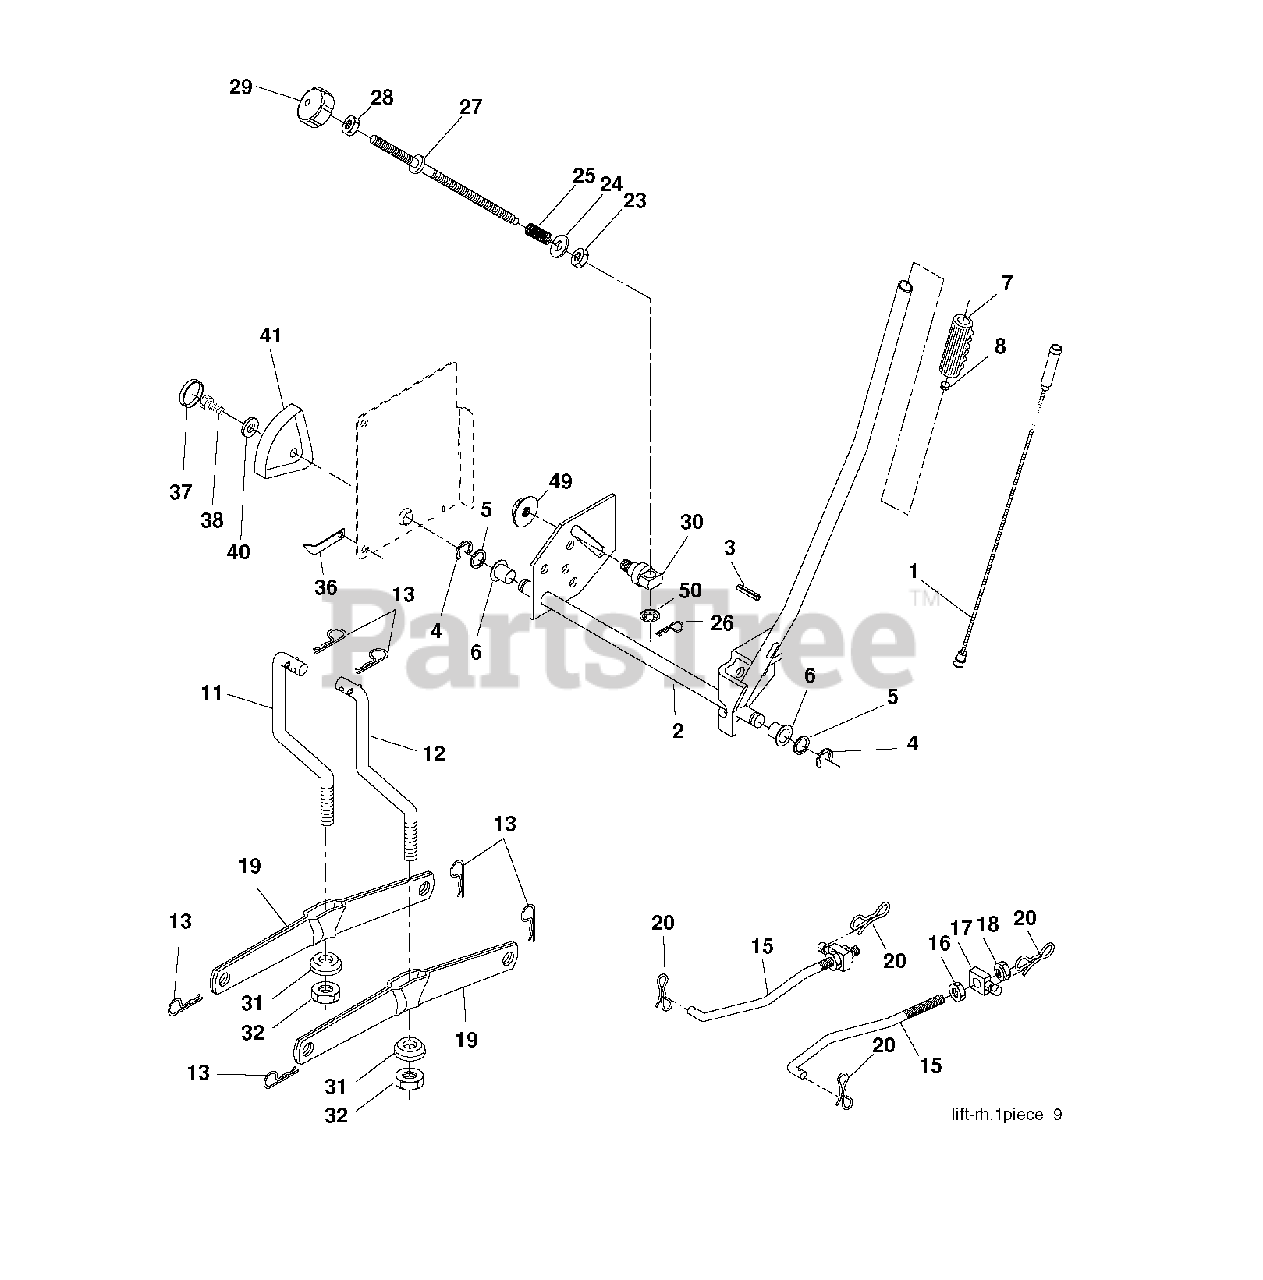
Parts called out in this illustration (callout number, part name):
1	PLUNGER.ASM.LIFT.LVR.BLK.17.32
2	SHAFT ASM R HANDLE
3	PIN GROOVE
4	RETAINING RING LT
6	BEARING.NYLON
7	GRIP HANDLE
8	PLUNGER BUT KIT
11	LINK
12	LINK
13	RETAINER-SPRNG RB
15	LINK.SUSPENSION.FRONT
16	NUT
18	NUT
19	ARM.REAR.SUSPENSION
20	PIN.COTTER.7/16.BOW TI
25	SPRING**
26	RETAINER CLIP
27	ROD ADJ LIFT
28	NUT
29	KNOB INF 3/8-16
31	BEARING.PIVOT.LIFT
32	NUT CROWNLOCK 3/8-24
36	POINTER, HEIGHT INDICATOR
37	PLUG,HOLE
38	SCREW 5/16-18X1
41	HEIGHT INDICATOR
49	NUT
50	NUT PUSH M
